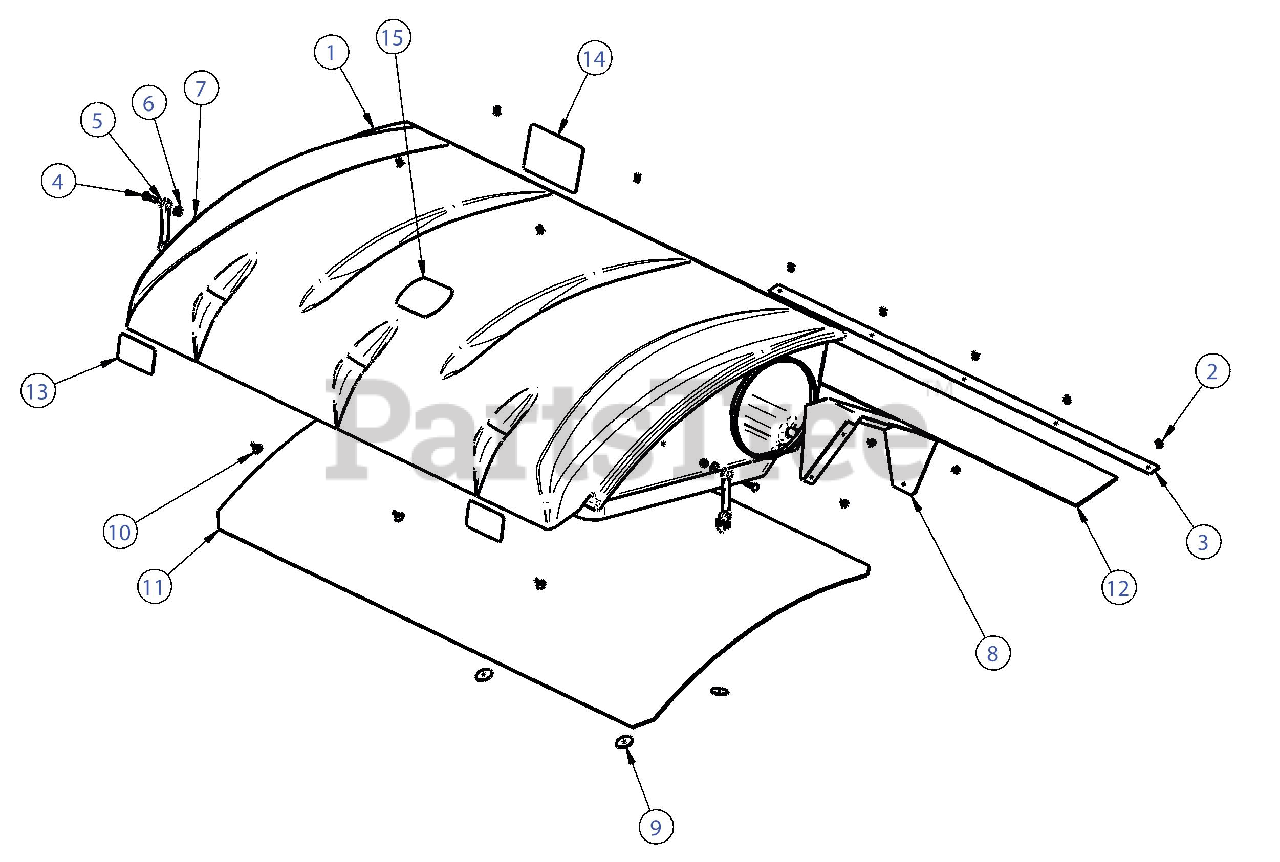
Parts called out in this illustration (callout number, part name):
1	PRO 3 BAGGER TOP
2	Black Plastic Rivet
3	Dust Guard Brace
4	1/4"-20 x 1-1/4" Carriage Bolt
5	Short Rubber Strap w/ S-Hook
6	Flat Washer / 1/4" (.75 OD x .312 ID x .060 T)
7	1/4"-20 Nyloc Nut
8	Grass Deflector
9	3/16" x 1-1/2" Fender Washer, Z
10	Black Panel Retainer
11	Black Plastic Screen
12	DUST GUARD
13	2" x 4" Red Reflector Label
14	Made In America Decal
15	Decal / Cub Cadet 'C'
